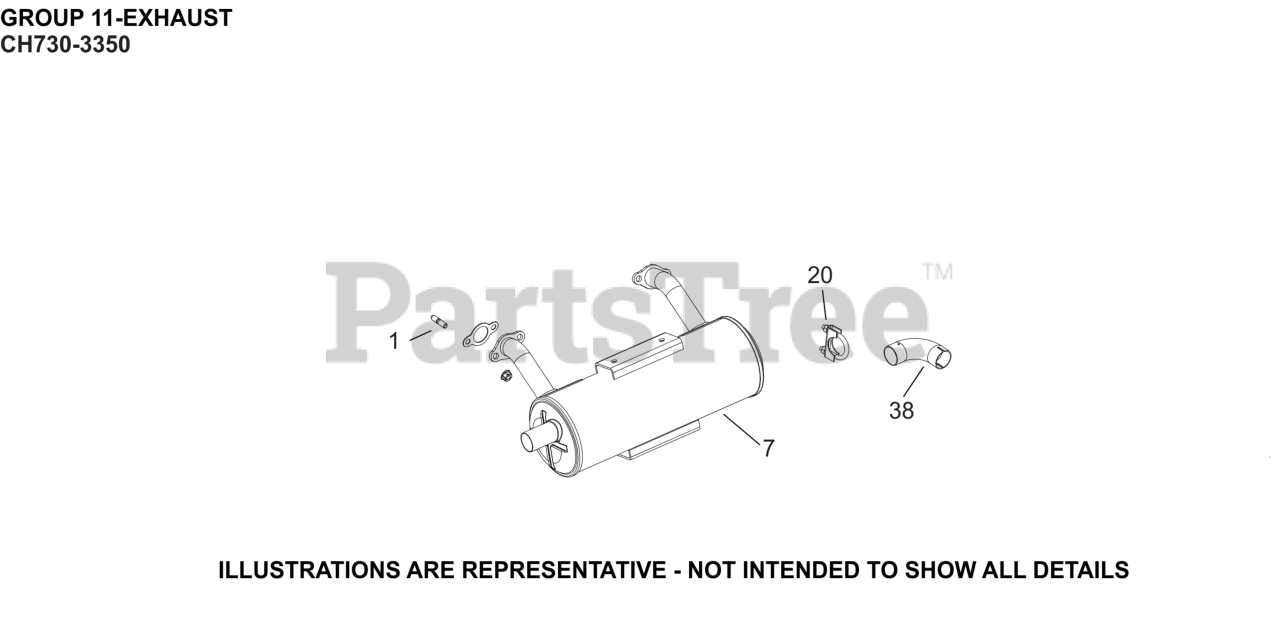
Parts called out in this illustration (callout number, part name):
1	STUD, METRIC EXHAUST
7	MUFFLER KIT, STARTER SIDE/STRAIGHT
38	ELBOW, EXHAUST
